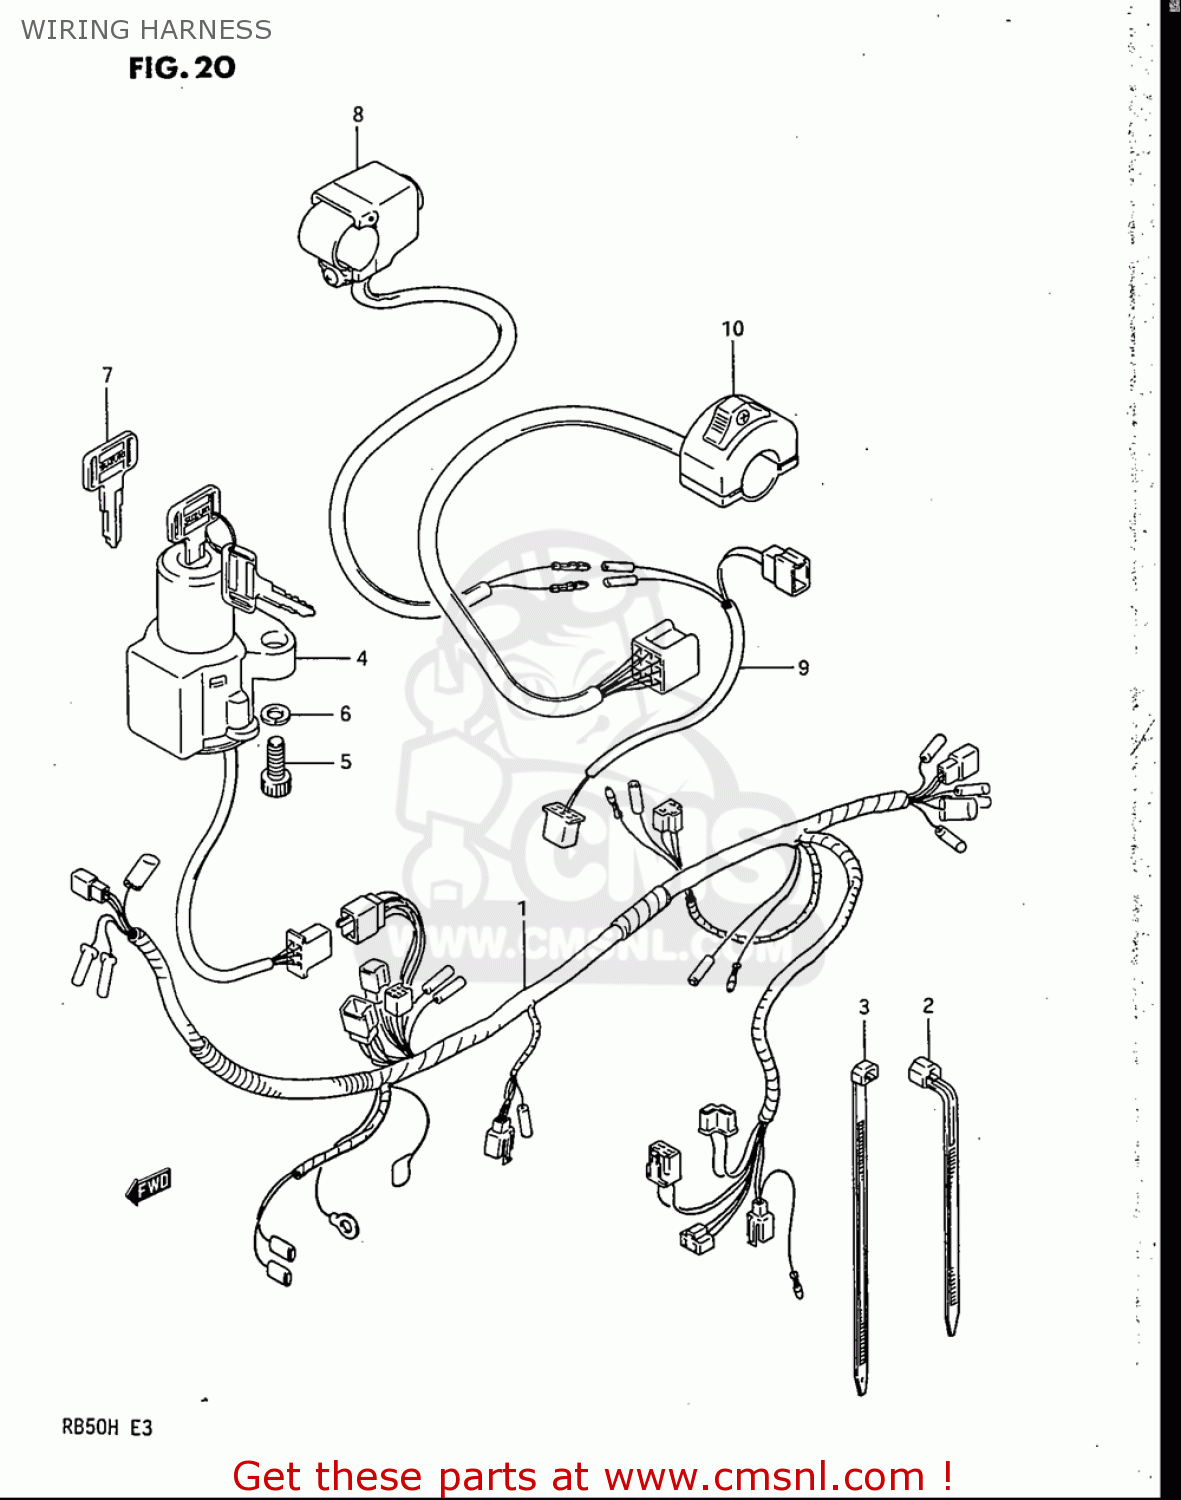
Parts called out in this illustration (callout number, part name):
2	CLAMP(L:125)
3	CLAMP
4	LOCK ASSY,STEERING
5	BOLT
6	WASHER,LOCK
7	KEY,BLANK
8	SWITCH ASSY,ENGINE STOP
